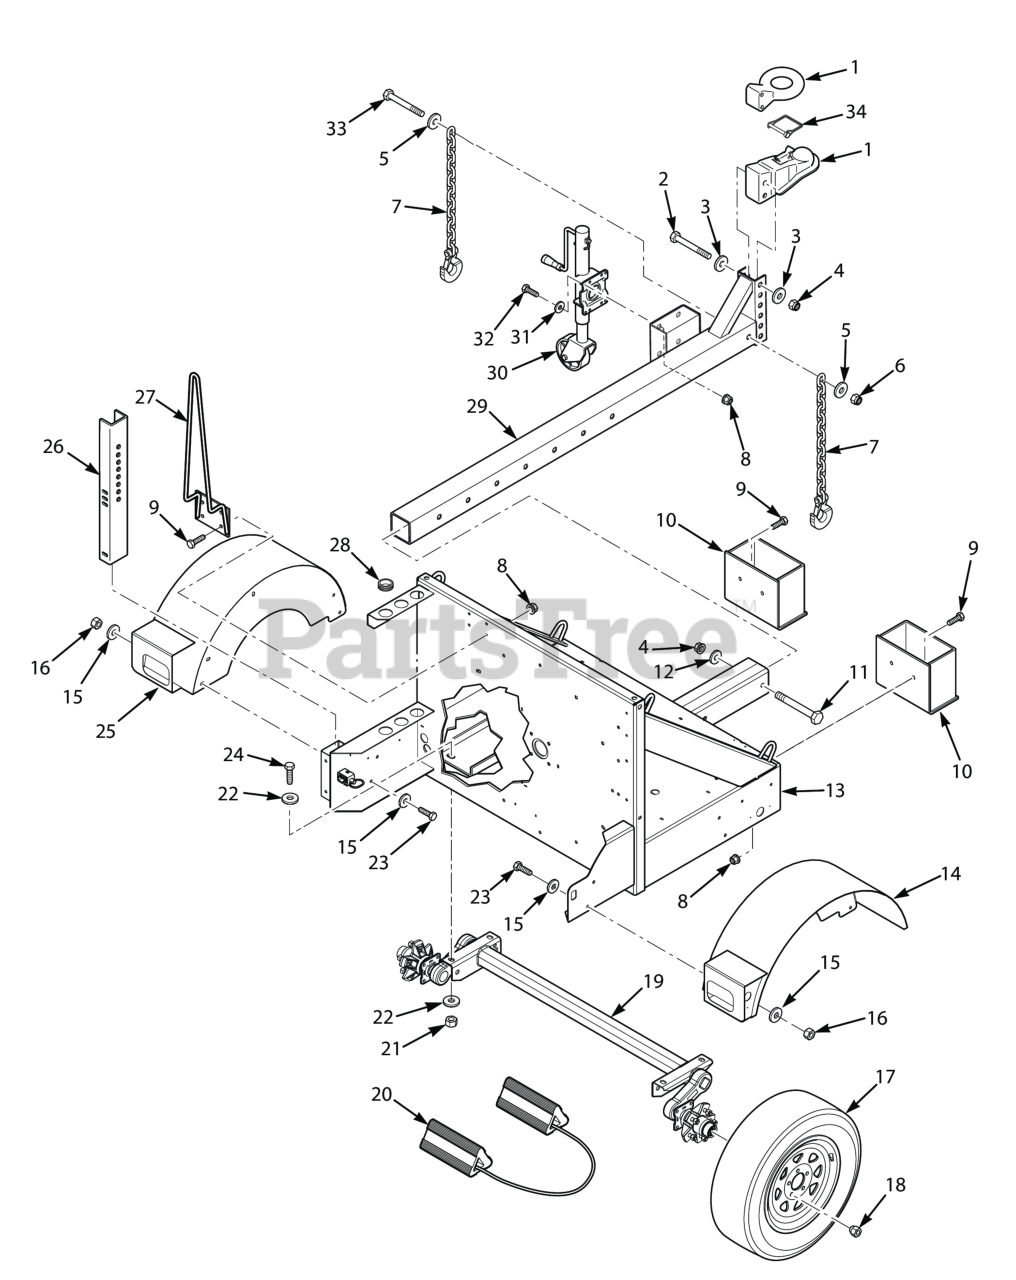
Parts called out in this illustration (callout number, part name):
1	Ball Coupler, 2-5/16"
2	Bolt, Hex Head 5/8-11 x 4-3/4" Grade 8
3	FW, 5/8 -.656X1.312X.095 HD
4	Nut, Center Lock 5/8-11
5	Flat Washer, 1/2 (.562 x 1.375 x .109)
6	LKNUT, M12-1.75 ELAS STOP
7	Safety Chain
8	NUT, 3/8-16 SERRATED FLANGE HEX HEAD
9	Bolt, Hex Head Serrated Flange 3/8-16 x 3/4"
10	Chock Box
11	BOLT, HEX HEAD, 5/8-11 X 5-1/2
12	Flatwasher, 5/8 - (..688 x 1.75 x .134)
13	Base and Frame w/Decals
14	Fender Weldment, RH
15	Flatwasher, 7/16" (.500 x 1.25 x .083")
16	HEX LOCKNUT, ELASTIC STOP, 7/16-14
17	Wheel Assembly, 205/75D15 - 6 Ply
18	Wheel Nut, 1/2-20 x 13/16
19	Axle, 3500 LBS. (incl. #18)
20	Wheel Chocks w/Rope
21	HEX LOCKNUT, ELASTIC STOP, 5/8-11
22	Flatwasher, 5/8-.688 x 1-3/4 x .134 HD
23	BOLT, HEX HEAD, 7/16-14 X 1-1/4
24	Bolt, Hex Head, 5/8-11 x 1-3/4"
25	Fender Weldment, LH
26	Support Channel
27	Holder, Traffic Cone
28	Grommet, Rubber
29	Drawbar Assembly w/Decal, TLB25 (INCL. 1,2, 3,4,5,6,7,8,30,31,32,33,34,Decal-485126)
30	Jack, Single Wheel
31	Flatwasher, 3/8" Special (.391 x .938 x .105)
32	Bolt, Hex Head, 3/8-16 x 1 Gr. 5
33	HHCS, M12-1.75 X 140 LG
34	Pin, Snapper
